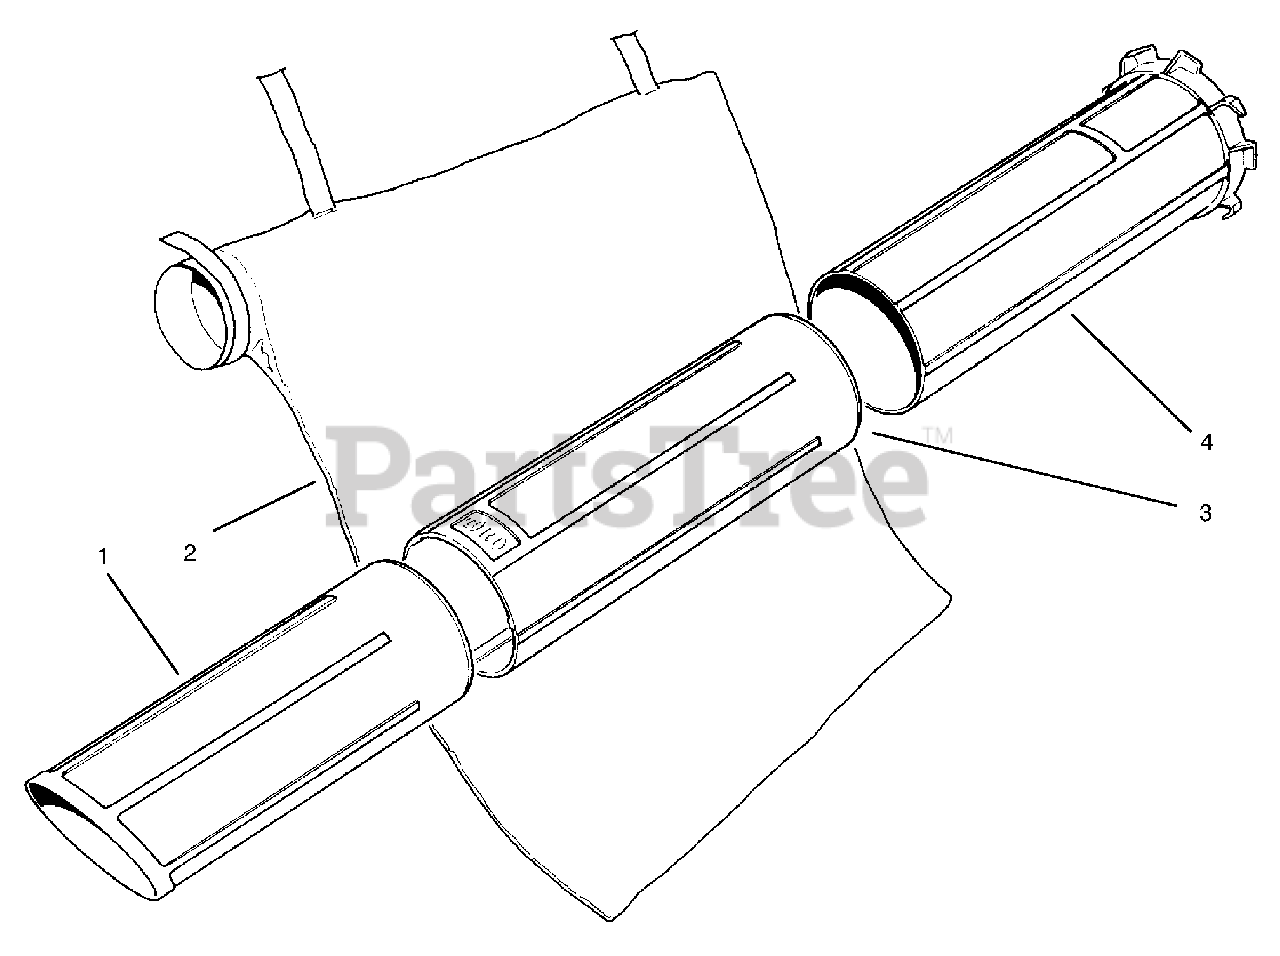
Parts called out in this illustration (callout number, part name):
1	Lower Vacuum Tube
2	Vacuum Bag
3	Middle Vacuum Tube
4	Upper Vacuum tube
